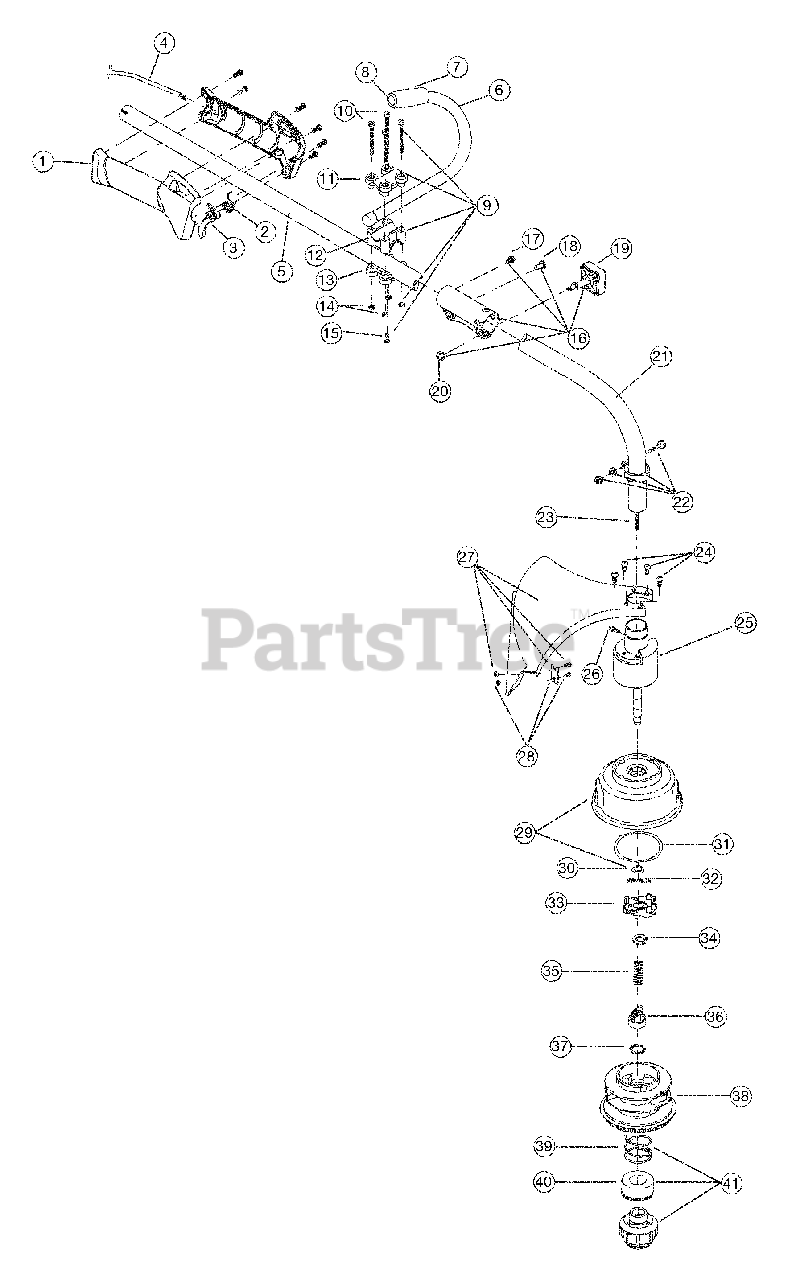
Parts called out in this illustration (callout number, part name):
1	Throttle Housing & Trigger Assembly
2	Throttle Trigger Spring
3	Throttle Trigger
4	Throttle Cable Assembly
5	Upper Drive Shaft Housing Assembly
6	J-Handle Assembly
8	Tube Closure
9	Handle Bracket Assembly
11	Upper Handle Clamp
12	Middle Handle Clamp
13	Lower Handle Clamp
15	Anti-Rotation Screw
16	Split Boom Assembly
19	Adjustment Knob
20	Knob Retaining Nut
21	Lower Drive Shaft Housing Assembly
22	Lower Clamp Assembly
23	Lower Flexible Drive Shaft
24	Shield Mounting Screw
25	Bushing Housing Assembly
26	Anti-Rotation Screw
27	Shield Assembly
28	Blade Assembly
29	Outer Spool Assembly
30	Retainer
31	Thrust Washer
32	Small Spring
33	Slider
36	Plunger
38	Inner Reel
39	Large Spring
40	Foam Seal
41	Bump Head Knob Assembly
